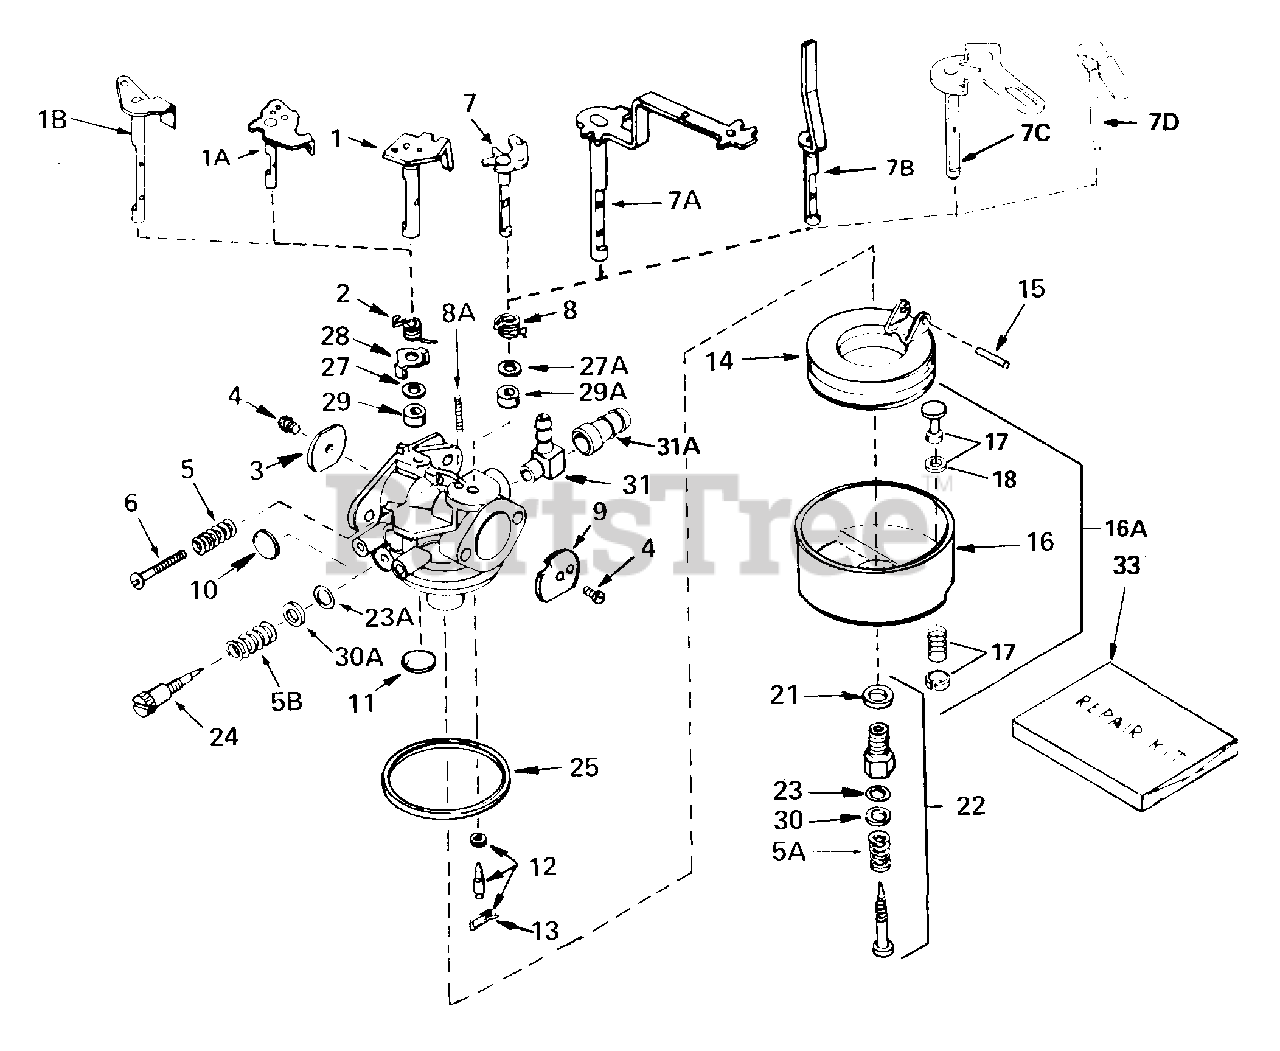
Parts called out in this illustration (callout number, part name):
1B	"Shaft & Lever Assy., Throttle
2	Spring, Throttle return
3	Shutter, Throttle
4	Screw, Throttle & Choke shutter
5	Spring, Adj.
5A	Spring, Adj. screw
5B	Spring, Adj. screw
6	Screw, Idle regulating
7A	Shaft & Lever Assy., Choke
8	Spring, Compression
8A	Spring, Choke positioning
9	Shutter, Choke
10	Plug, Welch
11	Plug, Welch
12	Inlet Needle, Seat & Clip Assy.
13	Clip, Inlet needle
14	Float, Carburetor
15	Shaft, Float
16	Bowl, Float
21	Gasket, Bowl-to-body
22	Adj. Screw Assy., Main
23	"O" Ring, Adj. screw
23A	"O" Ring, Adj. screw
24	Screw, Idle adj.
25	Gasket, Bowl-to-body
28	Retainer, Seal
29	Seal, Dust
29A	Seal, Dust
30	Washer, Flat
30A	Washer, Flat
33	Repair Kit
